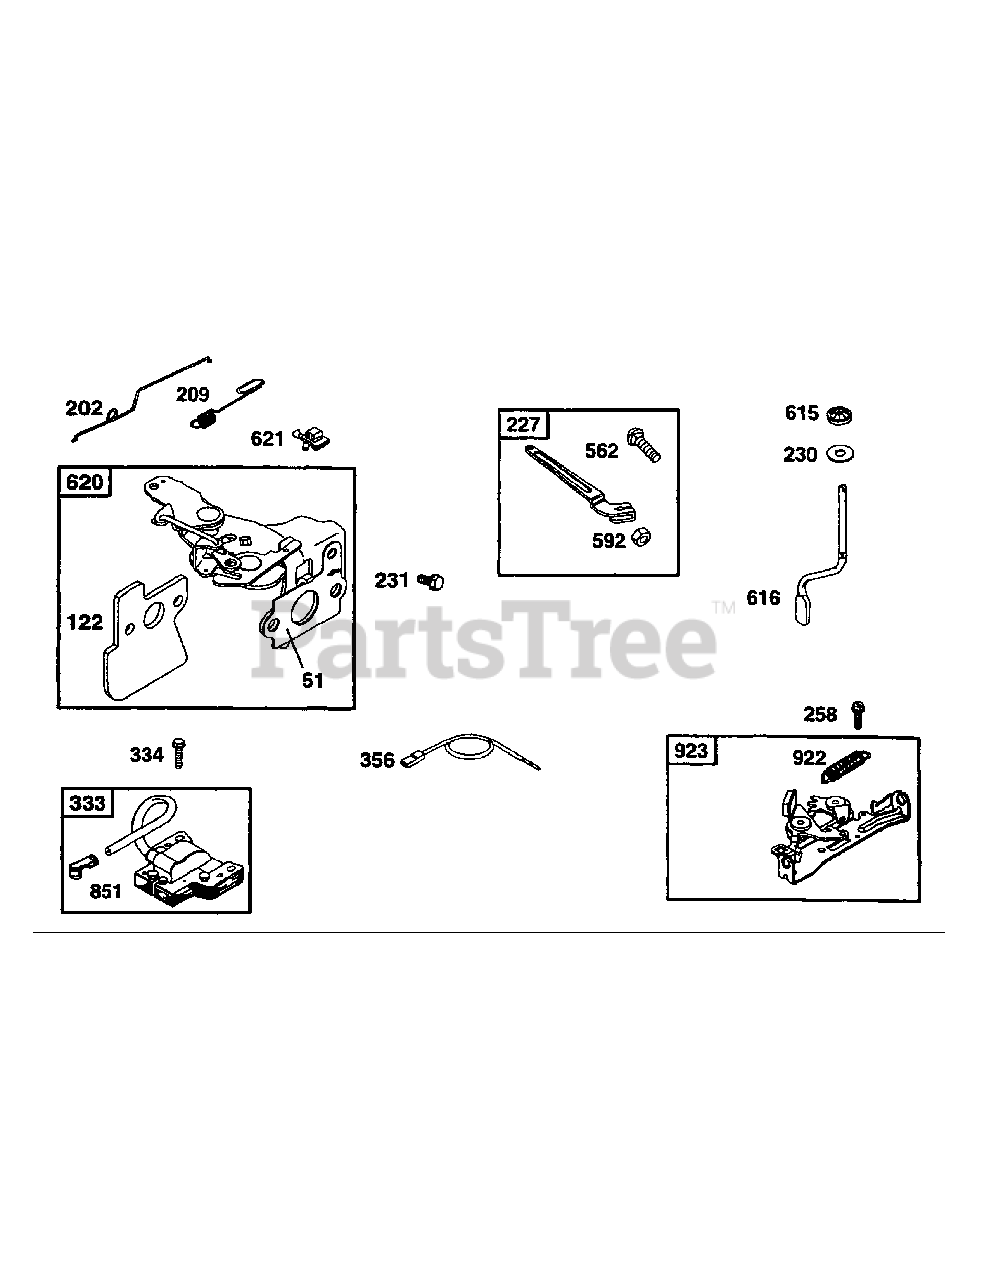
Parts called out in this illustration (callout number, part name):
51	Intake Gasket
122	Carburetor Spacer
202	Mechanical Gov. Link
209	Gov. Spring
227	Gov Lever
230	Flat Washer
231	Screw Hex
258	Slotted Hex Screw
333	Magneto
334	Screw Hex
356	Stop Wire
562	Gov. Lever Bolt
592	Hex Nut
615	Gov Retainer
616	Gov. Crank
620	Control Bracket
851	Cable Terminal
922	Brake Spring
923	Brake
